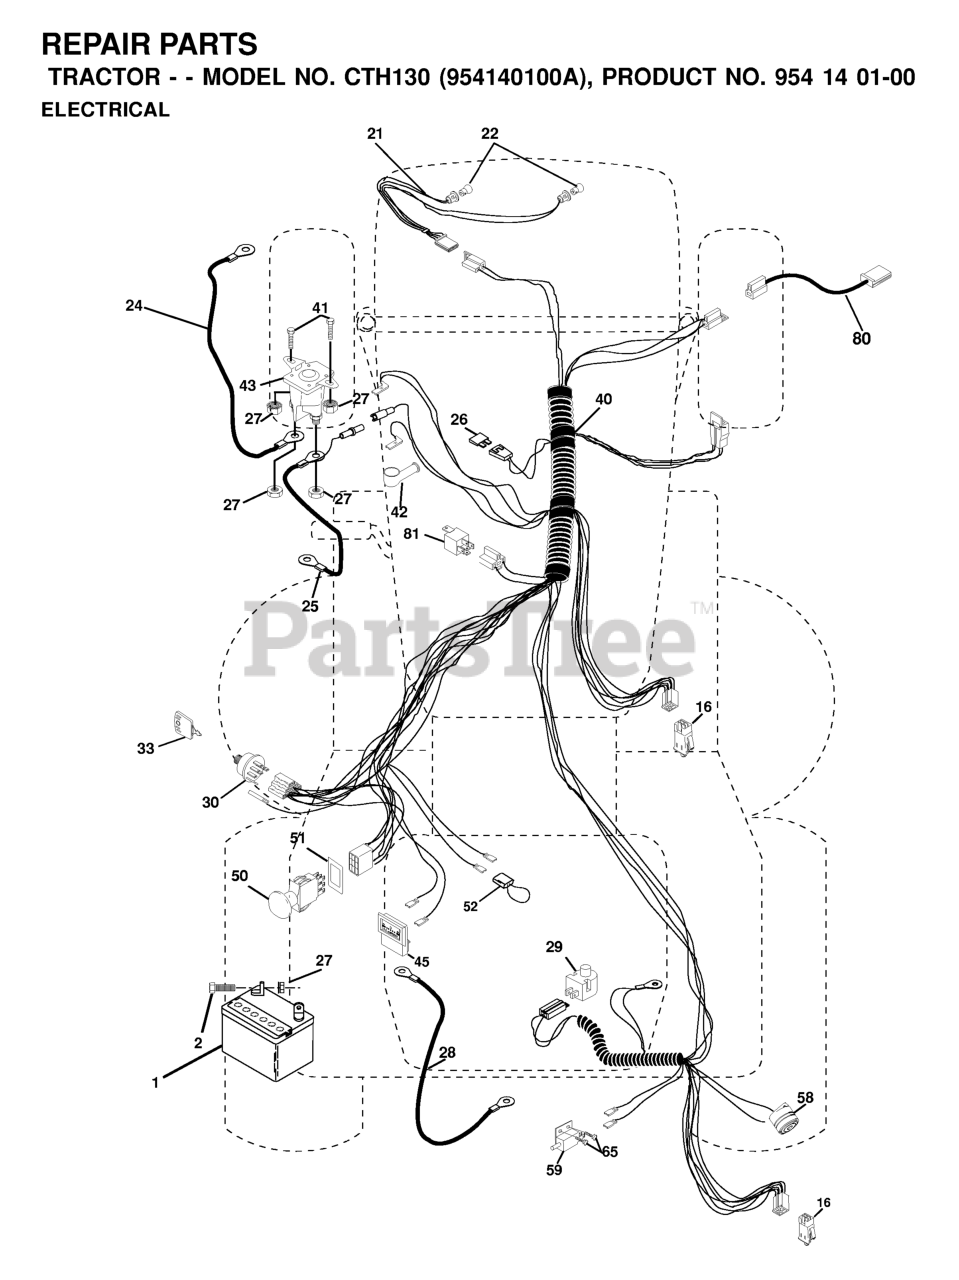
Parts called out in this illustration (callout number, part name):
1	BATTERY 12 VOLT 25 AMP
2	BOLT.HEX.1/4.X.3/4.DICHROMATE
8	CASE BATTERY MECH HINGE
16	SWITCH INTERLOCK
24	BATTERY CABLE GT
25	CABLE BATTERY
26	FUSE 20AMP
27	NUT
28	CABLE T
29	PLUNGER SWITCH (COLOR:OLIVE)
30	IGNITION SWITCH
33	KEY MLD GEN DELTA
40	HARNESS IGN.
41	BOLT
42	TERMINAL COVER
43	REPL BY 532 1461-54
46	HOUR METER
50	RP.PTO.SWITCH.8 TERMINAL.BLACK
51	FRAME RETAINING RING
80	HARNESS, CLUTCH
81	RELAY.ASSY.T
89	BRACKET SNAP-IN HOURMETER
